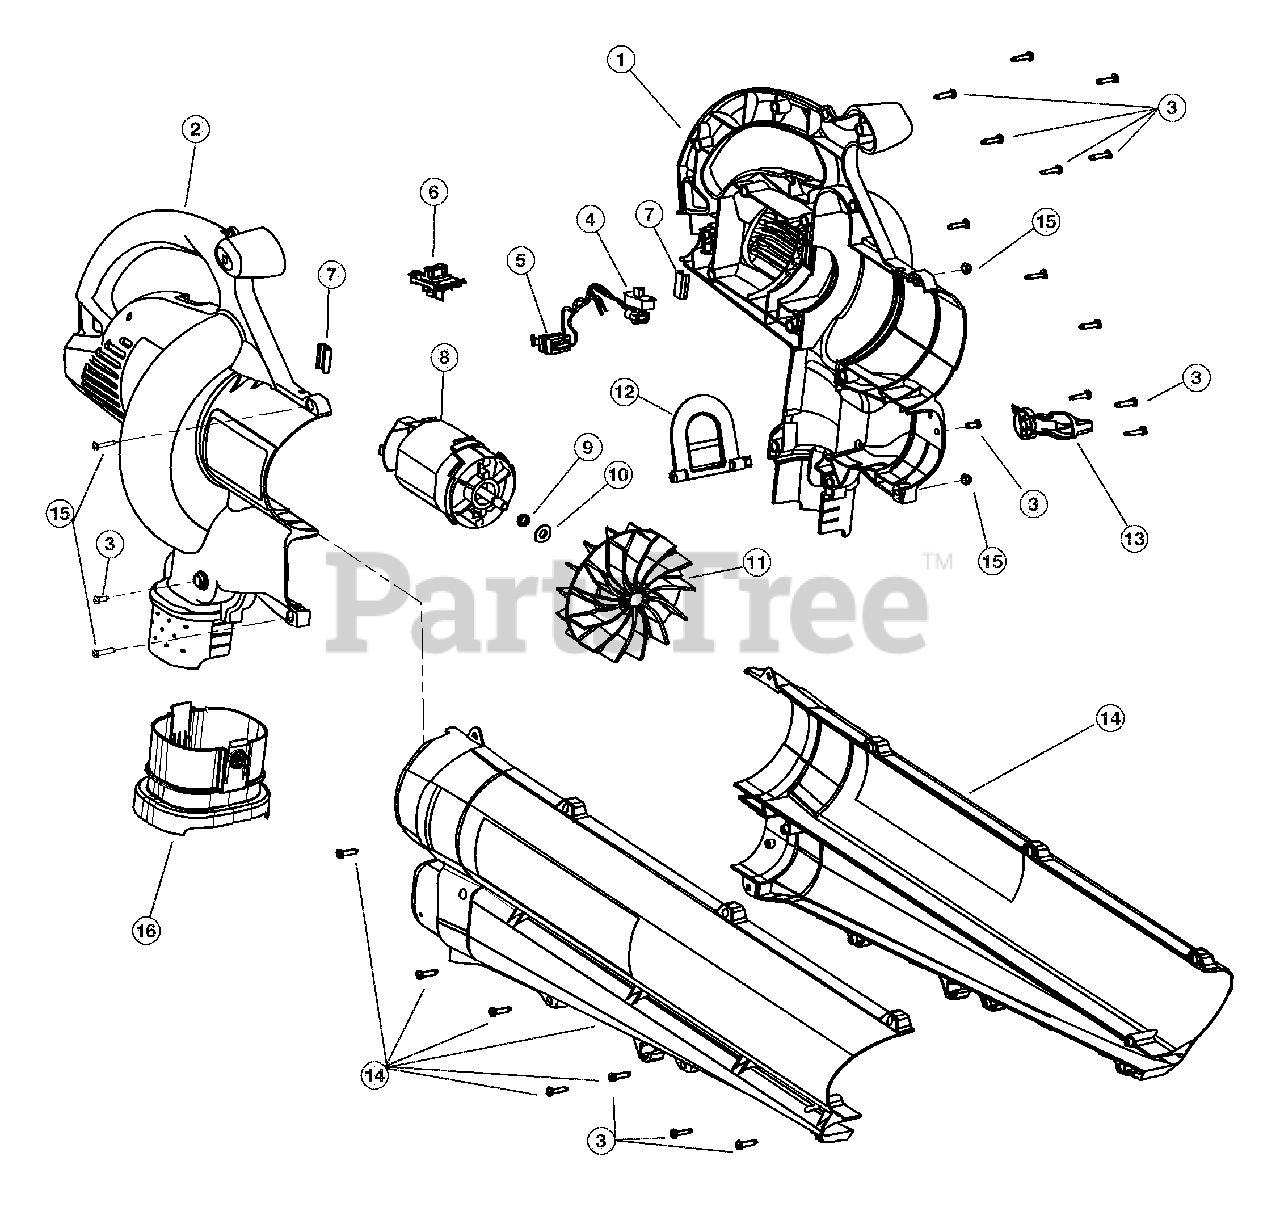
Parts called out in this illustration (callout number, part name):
1	Left Motor Housing
2	Right Motor Housing
3	Housing Screw
4	Switch Assembly
5	Power Connection Wire Assembly
6	Switch Lever
7	Rubber Cushion
8	Motor Assembly
12	Mode Control Flapper
13	Mode Control Lever
14	Blower/Vac Tube Assembly
15	Blower/Vac Tube Mounting Hardware
16	Vacuum Bag Adapter
